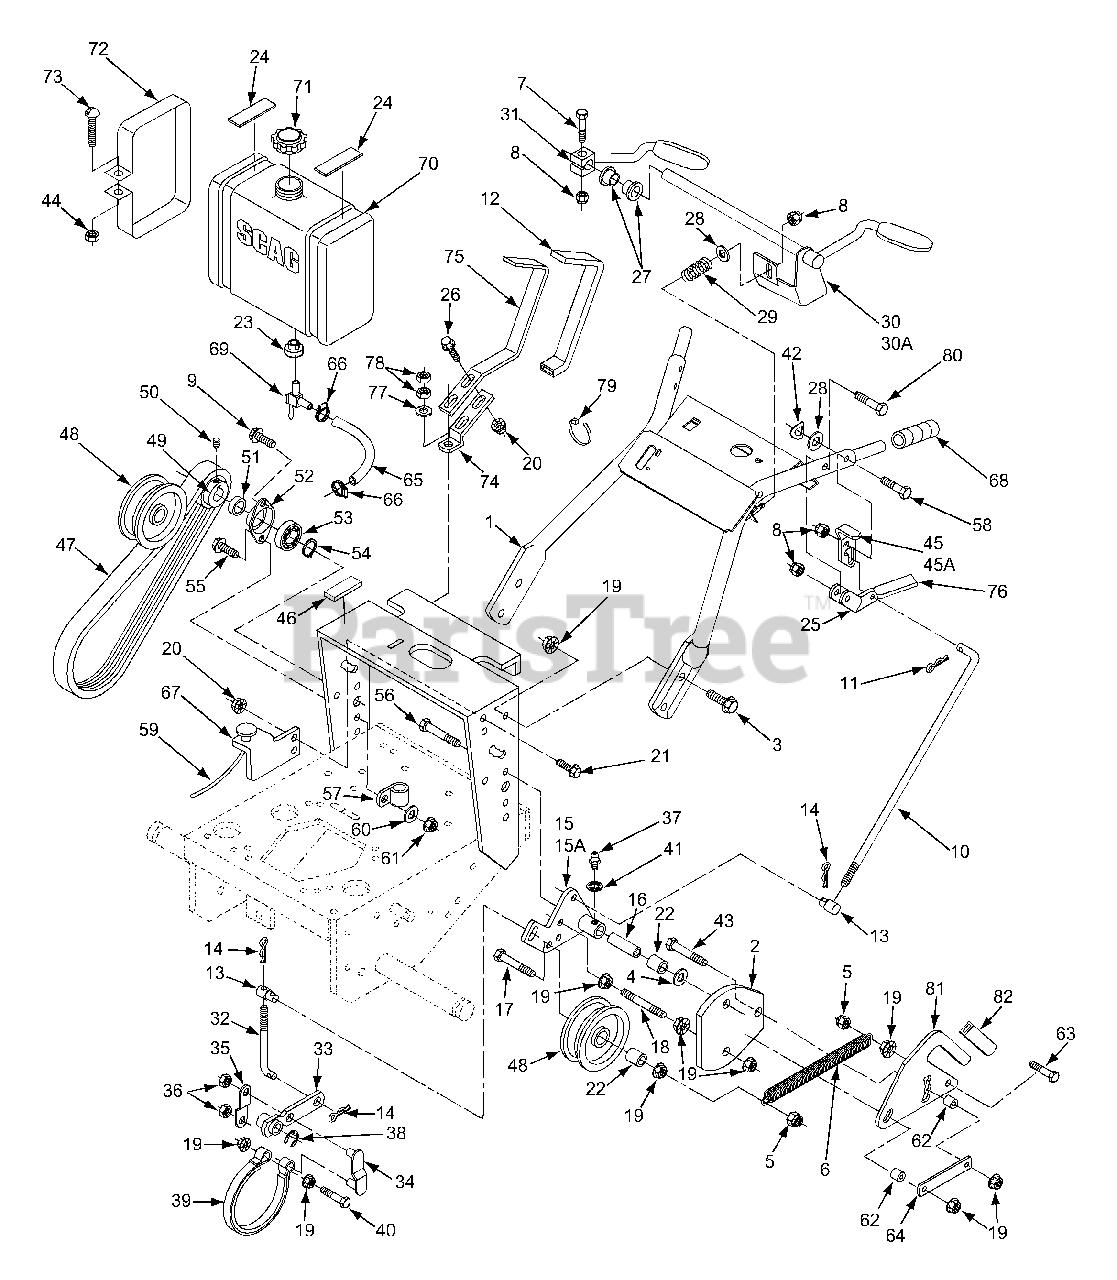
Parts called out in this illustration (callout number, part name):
1	Handle Assembly 16" Frame
2	Belt Guard
3	Capscrw, 3/8-16 x 1" Ser. Flange
4	Flatwasher, 3/8 (.391 x .938 x .105)
5	Nut, 3/8-16 Elastic Stop
6	Spring, Idler
7	Bolt, 5/16-18 x 1-1/4" Hex Head
8	Nut, 5/16-18 Elastic Stop
9	Capscrew, 1/4-20 x 3/4" Hex Head
10	Control Rod, Steering
11	Hair Pin, Small
12	Grip, Shift Lever
13	Swivel Joint
14	Hair Pin, Large .094 Diameter
15	Idler Bracket, RH
15A	Idler Bracket, LH
16	Idler Sleeve
17	Bolt, 3/8-16 x 3/4" Hex Head
18	Support Belt Guard
19	Nut, 3/8-16 Serrated Flange
20	Nut, 5/16-18 Serrated Flange
21	Cpscrw, 5/16-18 x .75" Ser. Flng.
22	Spacer
23	Bushing, Fuel Tank
24	Rubber Pad, (Upper)
25	Steering Lever
26	Capscrew, 5/16-18 x 1" Ser. Flng.
27	Bushing, Operator Presence
28	Washer, 5/16 (.375 x .875 x .083)
29	Spring, Operator Presence
30	Operator Presence Lever, LH (Small Frame)
31	Operator Presence Lever, RH
32	Brake Rod
33	Brake Lever
34	Brake Link
35	Brake Link Plate
36	Nut, 3/8 Push-on
37	Greese Fitting, Straight 1/4-28
38	Retaining Ring, 5/8 Ext. "E"
39	Brake Band
40	Bolt, 3/8-16 x 2" Hex Head
41	1/4" Internal Tooth Lockwasher
42	Curved Spring Washer
43	Bolt, Hex Head 3/8-16 x 1.25"
44	Nut, 1/4-20 Hex
45	Neutral Latch, RH
45A	Neutral Latch, LH
46	Rubber Pad (Lower)
47	Belt, Wheel Drive
48	Idler Pulley, Wheel Drive
49	Pulley, Jackshaft (Inc. 50)
50	Setscrew, Hex Socket Knurl Cup Pt. 5/16-18 (nylock)
51	Spacer, Jackshaft Pulley
52	Flange, Jackshaft Bearing
53	Bearing, Jackshaft
54	Retaining Ring, 5/8 Ext. Basic
55	Capscrew, 1/4-20 x 1" Ser. Flange
56	Bolt, 3/8-16 x 3.25"
58	Bolt, 5/16-18 x 2" Hex Head
59	Choke Control
60	Flatwasher, 5/16 (.375 x .875 x .083)
61	Nut, 1/4-20 Elastic Stop
62	Spacer
63	Bolt, Hex Head 3/8-16 x 1.25"
65	Fuel Hose,1/4" ID, 20" (KA )
66	Clamp, Fuel Hose
67	Bracket, Choke Mounting
68	Grip, Handle
69	Valve, Fuel Shut Off
70	Fuel Tank Assy.
71	Fuel Tank Cap
72	Strap, Fuel Tank
73	Screw, 1/4-20 x 2" Rnd Hd Slotted
74	Shift Lever
75	Shift Lever
76	Grip, Steering Lever
77	Washer, 3/8 (.391x .938 x .105)
78	Nut, 3/8-24 UNF
79	Cable Tie
80	Bolt, 5/16-18 x 2-1/2"
81	Lever, Traction Adjustment W/Grip
82	Grip, Traction Adjustment Lever
